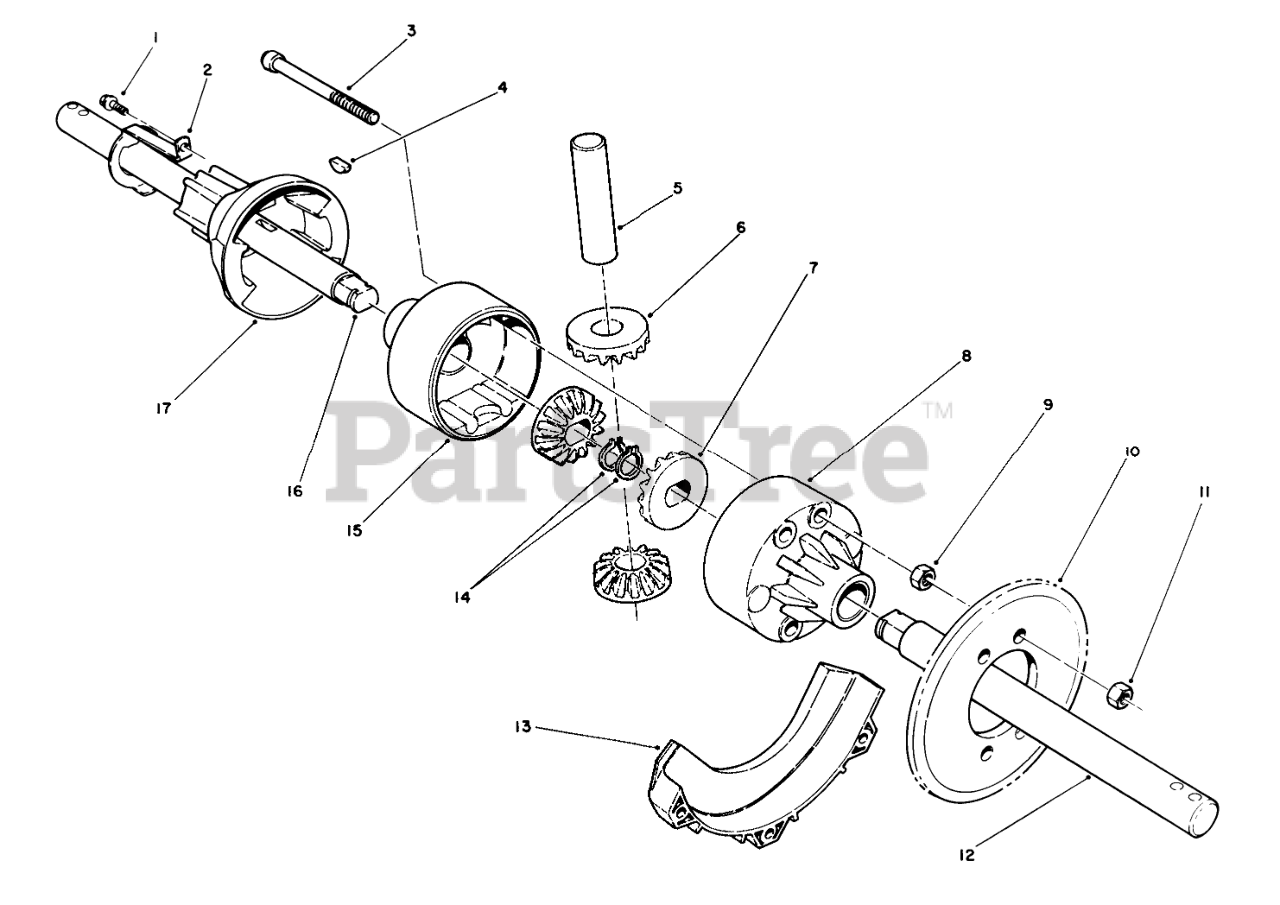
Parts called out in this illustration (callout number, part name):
1	SCREW-HWH
2	SPRING-LOCKOUT
3	SCREW-HSH
4	KEY-WOODRUFF
5	Shaft-Cross
6	Gear-Cross Shaft Pinion
7	Gear-Side Pinion
8	HOUSING ASSY - FEMALE
9	NUT-HEX
10	SPROCKET-27T
11	NUT-LOCK, NI
12	SHAFT - DIFFERENTIAL,LH
13	GUARD-CHAIN
14	RING-RETAINING
15	HOUSING ASSY - MALE
16	SHAFT - DIFFERENTIAL,RH
17	COUPLING-DIFFERENTIAL
